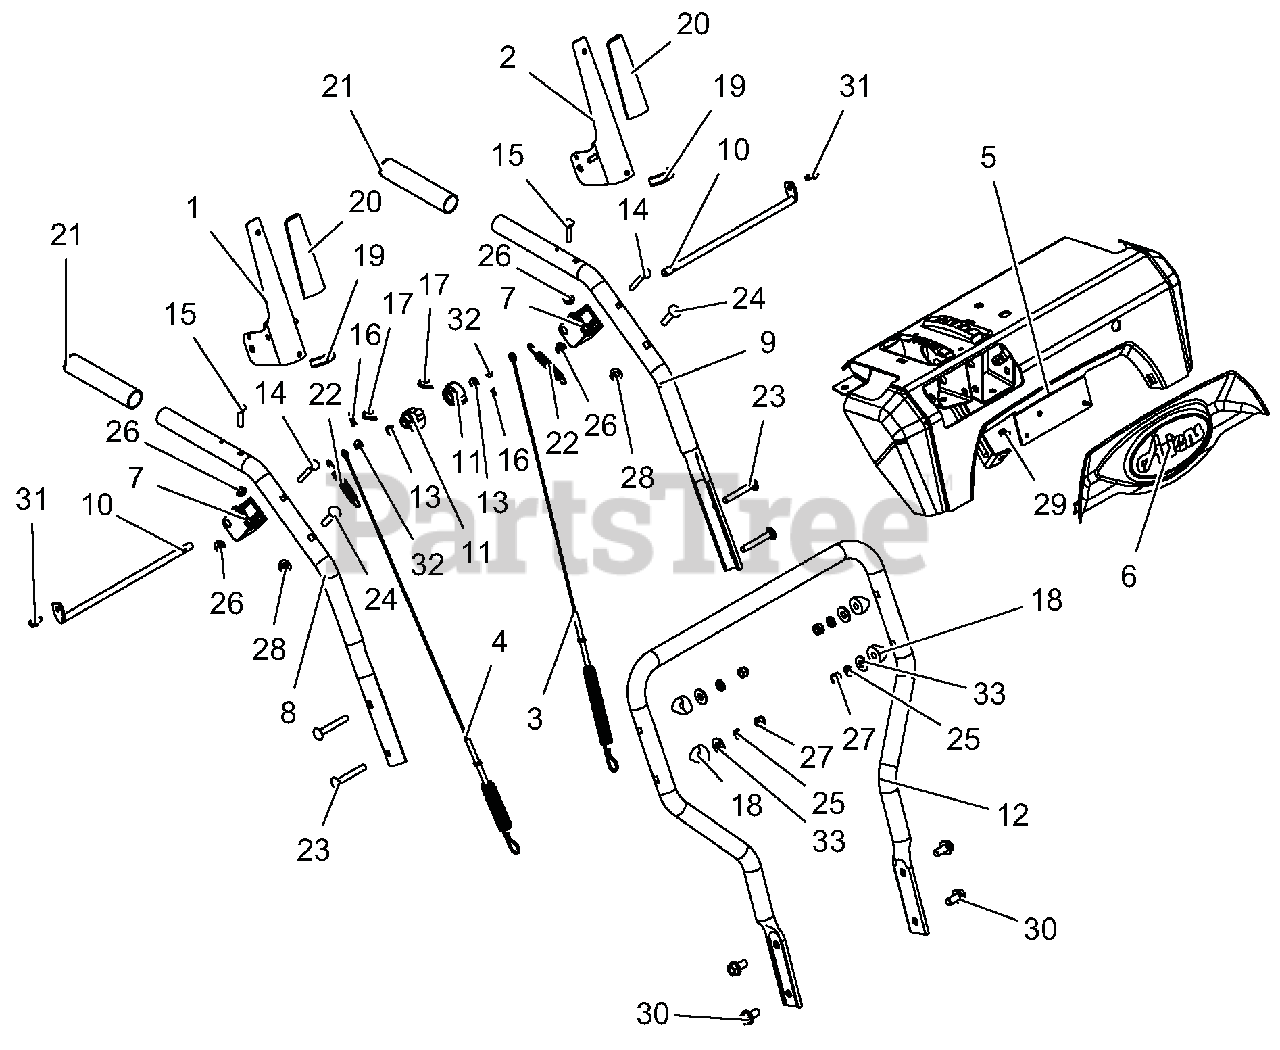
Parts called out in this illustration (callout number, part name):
1	LEVER, CLUTCH-RH
2	LEVER, CLUTCH-LH
3	CABLE, UPPER TRACTION
4	CABLE, AUGER (DELUXE & PRO)
5	CONTROL PANEL W/DECAL ID,AT
6	DASH BEZEL, ARIENS LOGO - PRO
7	BLOCK, CLUTCH PADDLE
8	HANDLEBAR, UPPER - RH
9	HANDLEBAR, UPPER - LH
10	ROD, PADDLE MOUNT - PRO
11	CAM, INTERLOCK
12	HANDLEBAR, LOWER - DELUXE
13	BUSHING, POLYLINER-.38 SNAPIN
14	BLT-RDHDXLSQNK .25-20X2.0 G5YZ
15	BLT-RDHDXLSQNK.25-20X1.25 G5ZC
16	PIN-HAIR INT .06X.18X.77
17	PIN, SPRING CLIP
18	SPACER, HANDLEBAR
19	EDGING, CLUTCH PADDLE - 2.00"
20	CLUTCH PADDLE SLEEVE - GRAY
21	HANDLE GRIP
22	SPRING, EXTENSION
23	@BLT-RDHDSQNK .31-18X2.25 G5YZ
24	@BLT-RDHDSQNK .31-18X1.50 G5YZ
25	WSHR-LK .312X.097 HVY YWZC
26	@NUT-LK-CTR-FLG .25-20 YWZC
27	@NUT-LK-NYL .312-18 YWZC
28	@NUT-LK-TOP-FLG .31-18 YWZC
29	SCR-TAP #10X.50 BOSS INDHXHD
30	BLT-SERHFWH .38-16X.75 YWZC
31	SCR-TAP .25-20X.50 HWH TR YWZ
32	@WSHR-FL-STL.281X.62X.065 YWZC
33	@WSHR-FL-STL.38X.875X.083 YWZC
